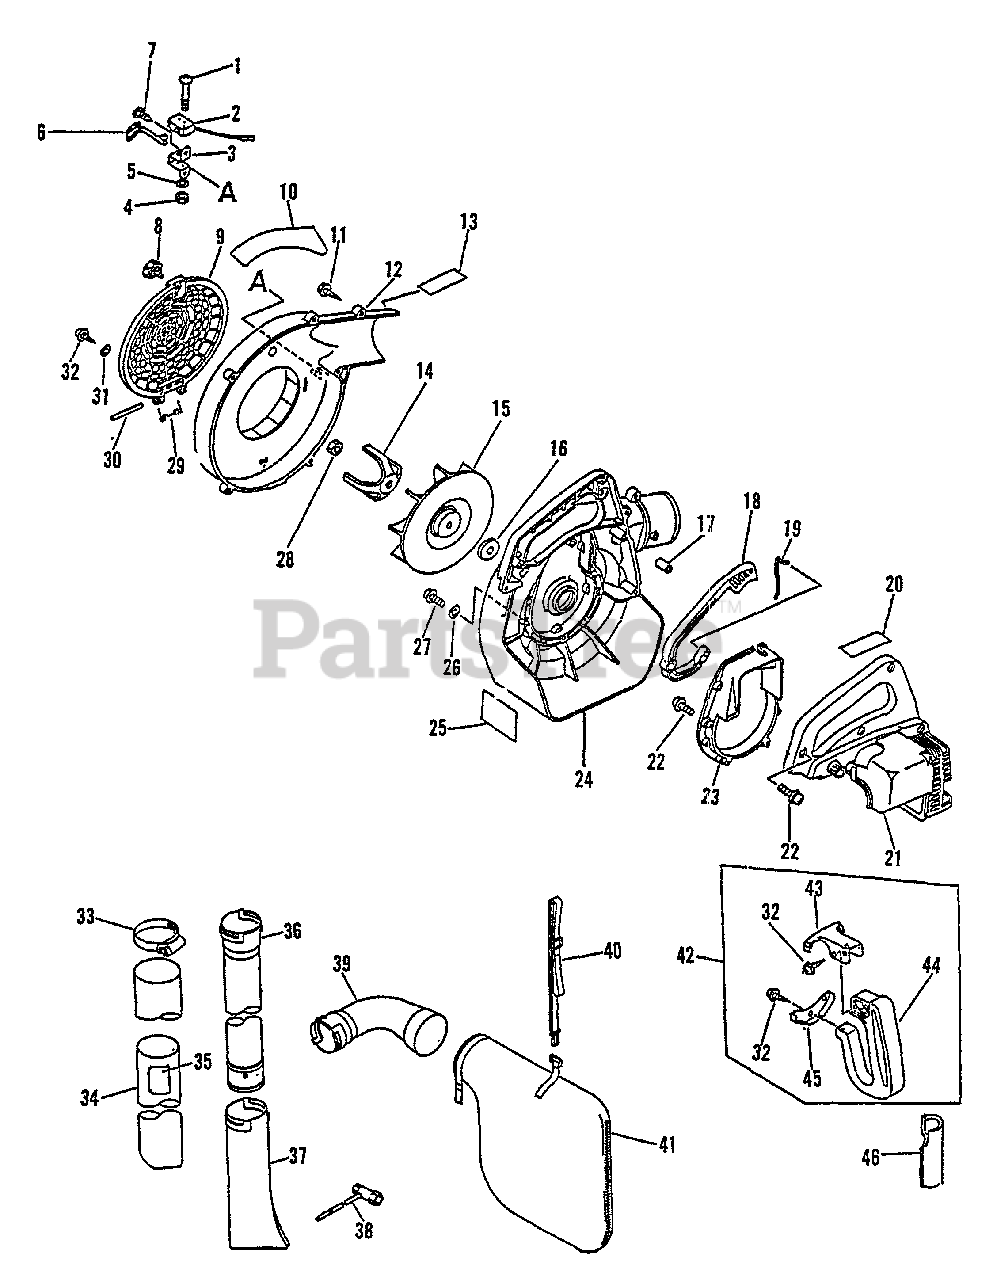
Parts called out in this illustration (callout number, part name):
1	SCREW
2	IGNITION SWITCH ASSY
3	BRACKET, SWITCH
5	LOCKWASHER
6	ACTUATOR
7	SCREW - 5X10
8	THUMBSCREW
9	GUARD, DEBRIS
10	LABEL - CAUTION
11	SCREW - 5X20 -- TAPPING
12	COVER, FAN - LEFT
13	LABEL - MODEL ES-2000
14	BLADE, SHREDDER
15	FAN
16	WASHER - 8
17	TUBE, RETAINER
18	TRIGGER, THROTTLE
19	ROD, THROTTLE
20	LABEL - HOT SURFACE
21	COVER, ENGINE
22	SCREW - 4X18
23	BRACKET, ENGINE
24	COVER, FAN - RIGHT
25	LABEL - CAUTION
27	SCREW - 4X22
32	SCREW - 5X14
34	TUBE, VACUUM
35	LABEL - MODEL
36	TUBE, BLOWER - STRAIGHT
37	NOZZLE - FAN HEAD
38	T-WRENCH - 8X19mm
39	TUBE, DEBRIS
40	SHOULDER STRAP ASSY
41	BAG, DEBRIS
42	HANDLE ASSY - REAR
43	BRACKET, HANDLE - UPPER
44	HANDLE
45	BRACKET, HANDLE - LOWER
46	GRIP, HANDLE
